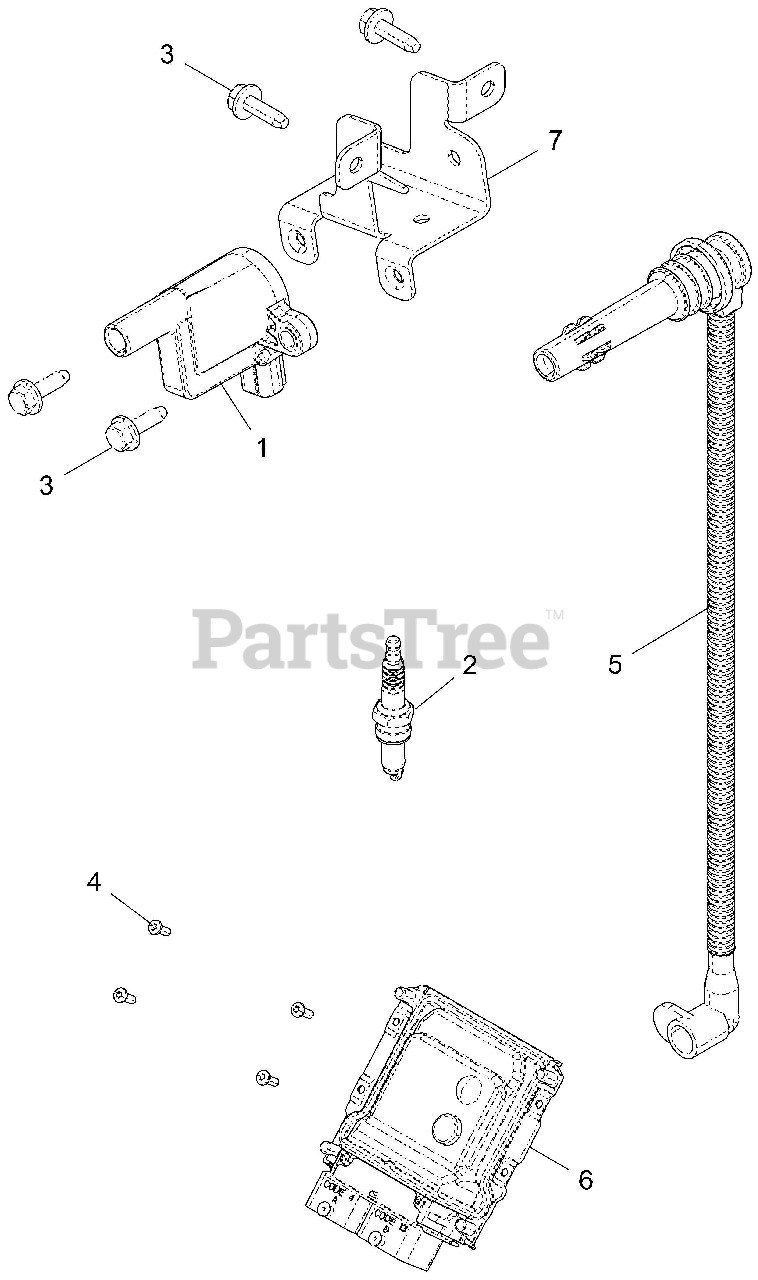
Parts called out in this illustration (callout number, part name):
1	COIL-IGNITION
2	SPARK PLUG-10 MM
3	SCR-M6X1.0X20,HXHD,FLG,TDFM,BL
4	SCR-#10X1/2-HI/LO-PN-T25,TRX-M
5	WIRE-SPARKPLUG,PTO
6	ECM-NO START,ME17
7	BRKT-AIRBOX MOUNT
